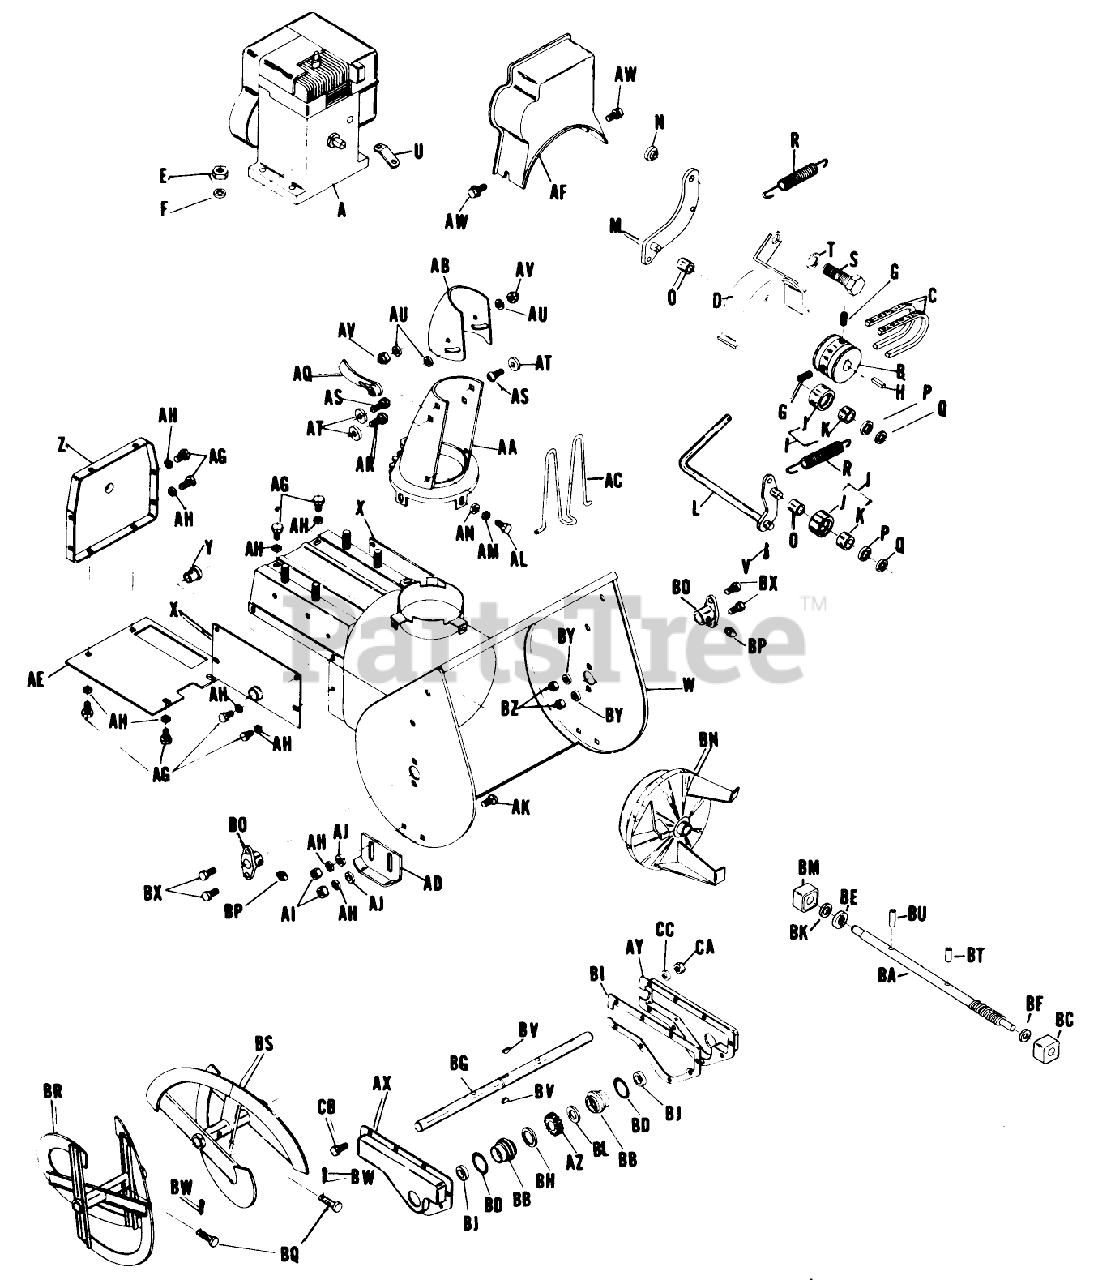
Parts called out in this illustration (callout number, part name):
A	Engine, 4 HP. BS Model 100202, Type 0434-01
D	Belt Guide
E	5/16-18 Hex. Nut, Plated
F	5/16 Spring Lock Washer, Plated
G	5/16-18 x 5/16 Socket Set Screw
H	3/16 x 3/16 x 1 1/4 Key
S	1/2-20 x 1 1/4 Hex. Hd. Cap Screw, Plated
T	1/2 Spring Lock Washer, Pl.
V	1/8 x 3/4 Cotter Pin, Plated
W	Auger Wrap Main Frame Assembly
Z	Backing Plate Assembly
AA	Chute Ring Assembly
AG	5/16-18 x 1/2 Hex. Hd. Cap Screw, Pl.
AH	5/16 Spring Lock Washer, Pl.
AI	5/16-18 Hex. Nut, Plated
AJ	5/16 Flat Washer, Plated
AK	5/16-18 x 3/4 Carriage Bolt, Plated
AL	1/4-20 x 35 Hex. Hd. Cap Screw, Plated
AM	1/4 Spring Lock Washer, Pl.
AN	1/4 SAE Flat Washer, Plated
AS	3/8-16 x 35 Carriage Bolt, Pl.
AT	1/2 Flat Washer, Plated
AU	3/8 Flat Washer, Plated
AV	3/8-16 Cone Lock Nut, Pl.
BG	Output Shaft
BN	Impeller, Pulley Assembly
BR	Auger Assembly, R.H.
BS	Auger Assembly, L.H.
BT	1/4 x 1" Roll Pin
BU	1/4 x 1 1/4 Roll Pin, Plated
BV	1/8 x 1/2 Woodruff Key, Alloy H.T.
BW	3/32 x 3/4 Cotter Pin, Plated
BX	5/16-18 x 3/4 Hex Hd Cap Screw, Plated
BY	5/16 Spring Lock Washer, Pl.
BZ	5/16-18 Hex Nut, Plated
CA	1/4-20 Hex Nut
CB	1/4-20 x 1/2 Hex. Hd. Cap Screw
CC	1/4 Spring Lock Washer
